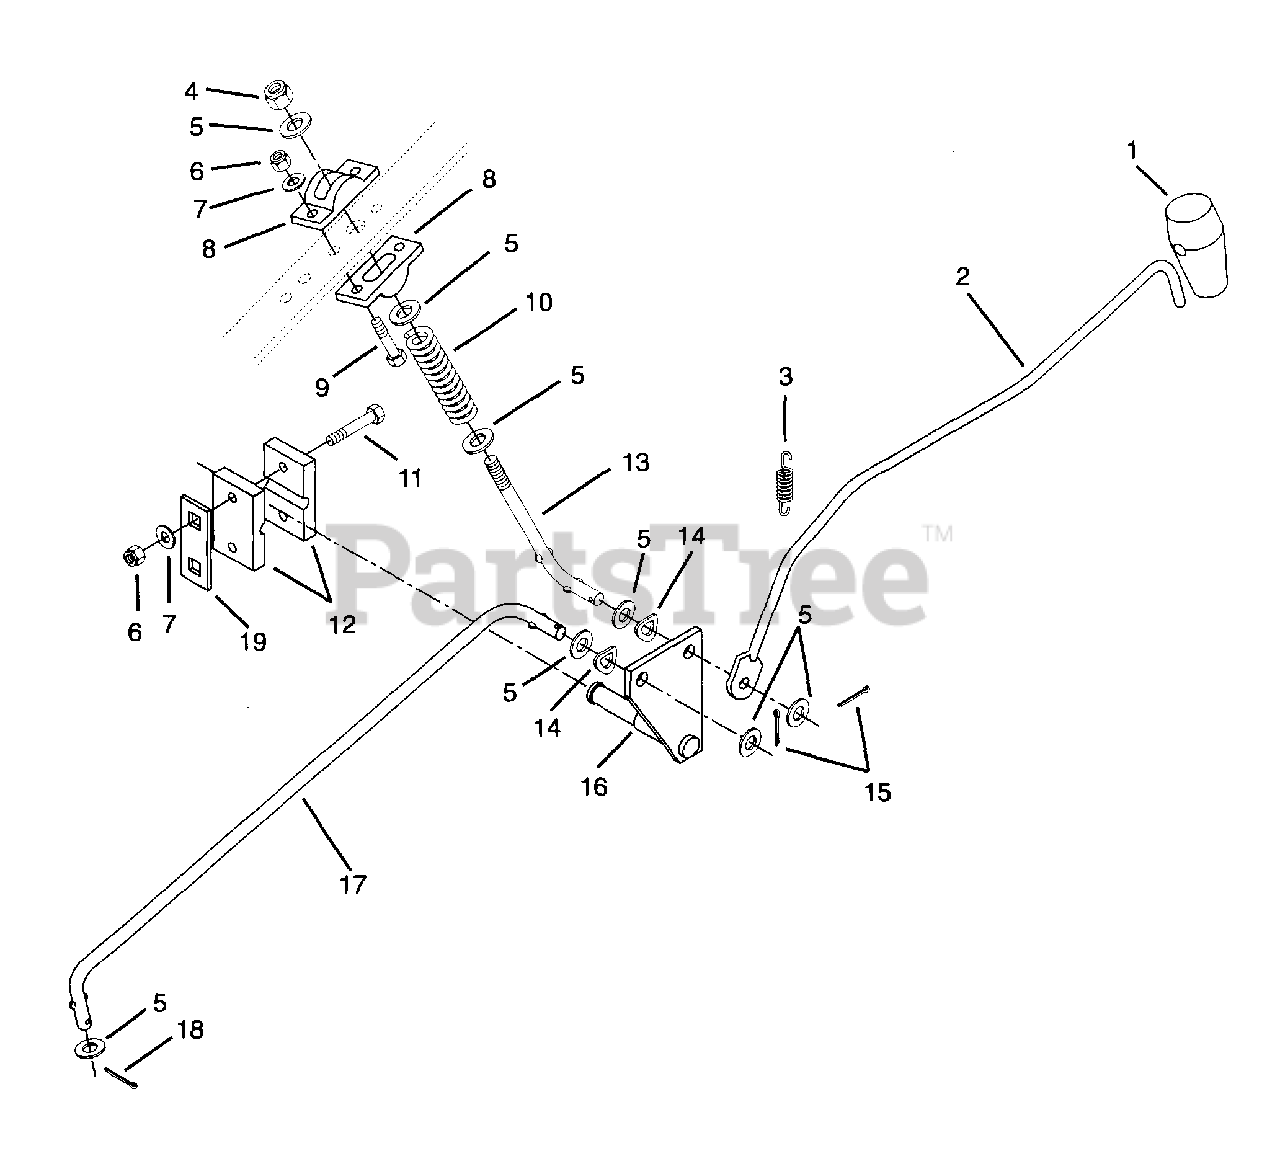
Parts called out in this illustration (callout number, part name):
1	Handle Rubber Shifter
2	Rod, Shifter
3	Spring-Tension .041 x 1.25 x .50
4	Nut-Locking-Center .375-16 Grade 2
5	Washer-Flat-Steel .406 x .812 x .065
6	Nut-Locking-Center .250-20 Grade 2
7	Washer-Flat-Steel .281 x .620 x .065
8	Cam, Shifter
9	Bolt-Hex .25-20 x 1.00 Grade 5
10	Spring-Compression .081 x .720 x 2.75
11	Bolt-Hex .25-20 x 1.50 Grade 5
12	Block, Shift Lever
13	Link, Shifter Stop
14	Spring Washer
15	Pin-Cotter .12 x .75
16	Weldment, PTO Bellcrank
17	Link, PTO Control
18	Pin-Cotter .09 x .75
19	Shim, Mower Height Adjuster Bracket
